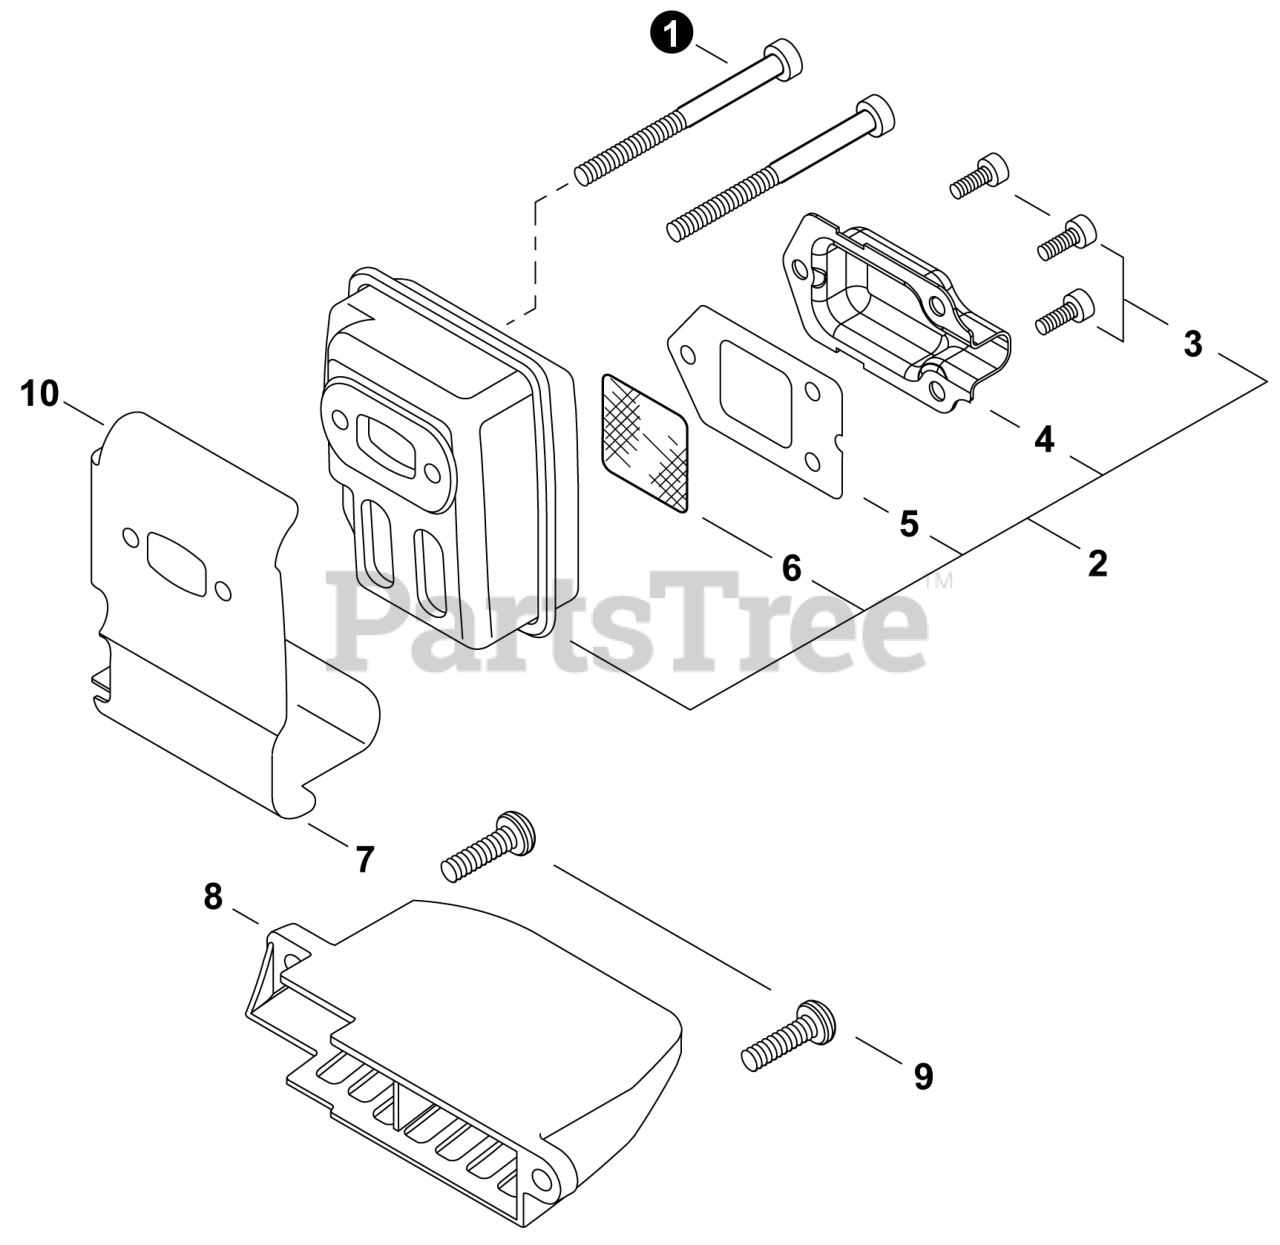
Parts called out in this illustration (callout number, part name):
1	BOLT, TORX 5x55
2	MUFFLER ASSY
3	BOLT, TORX 4x8
4	GUIDE, EXHAUST
5	GASKET, EXHAUST
6	SCREEN, SPARK ARRESTER
7	HEAT SHIELD, EXHAUST
8	COVER, MUFFLER
9	BOLT, TORX 5x16
10	GASKET KIT: ENGINE, INTAKE, EXHAUST
